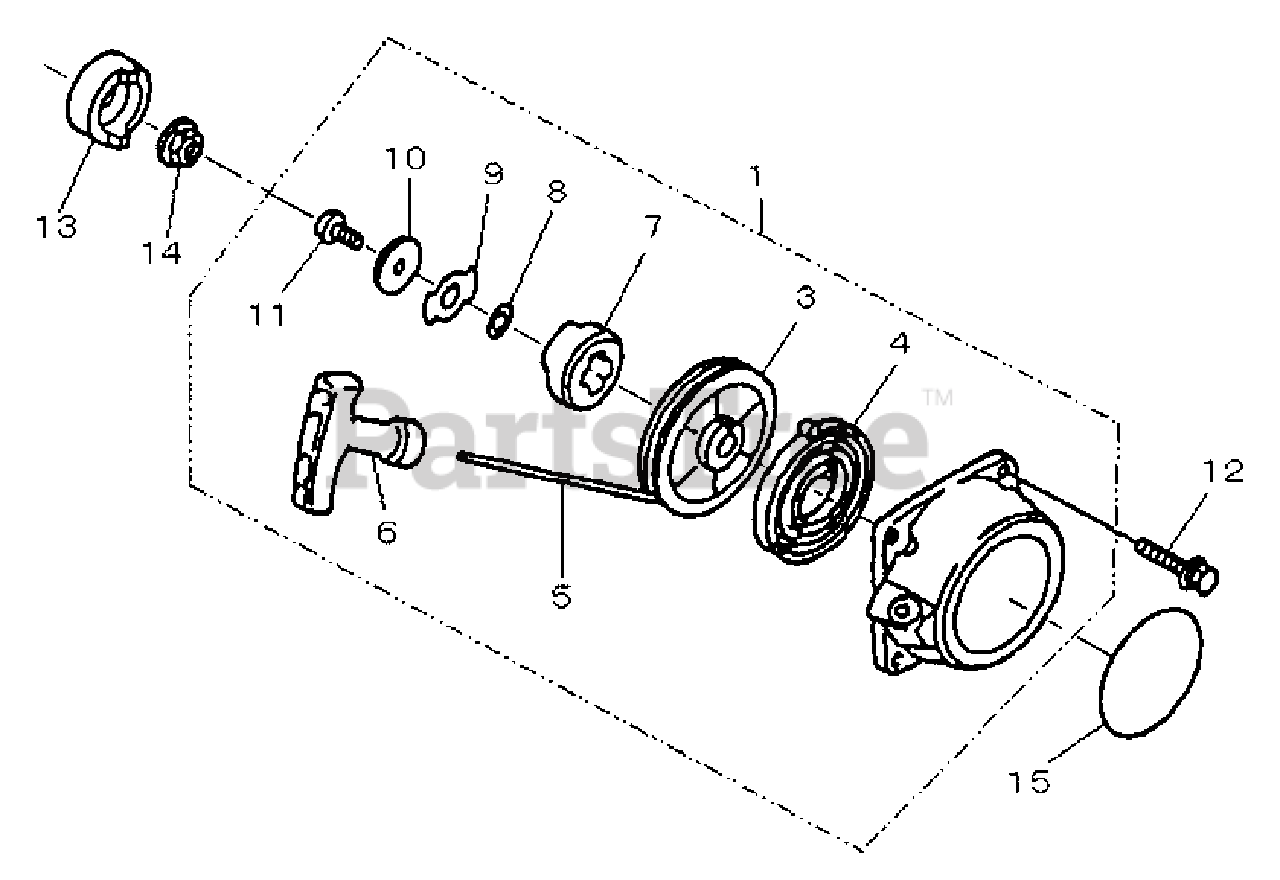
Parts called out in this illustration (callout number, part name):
1	STARTER ASSY
3	REEL, ROPE
4	SPRING, REWIND
5	ROPE, STARTER
6	GRIP, STARTER
7	CATCHER, PAWL
9	RETAINER
11	SCREW - 8 X 1-1/4"
12	BOLT - 5X20
13	PAWL, STARTER
14	NUT - 10 -- FLANGE
15	LABEL - MODEL
